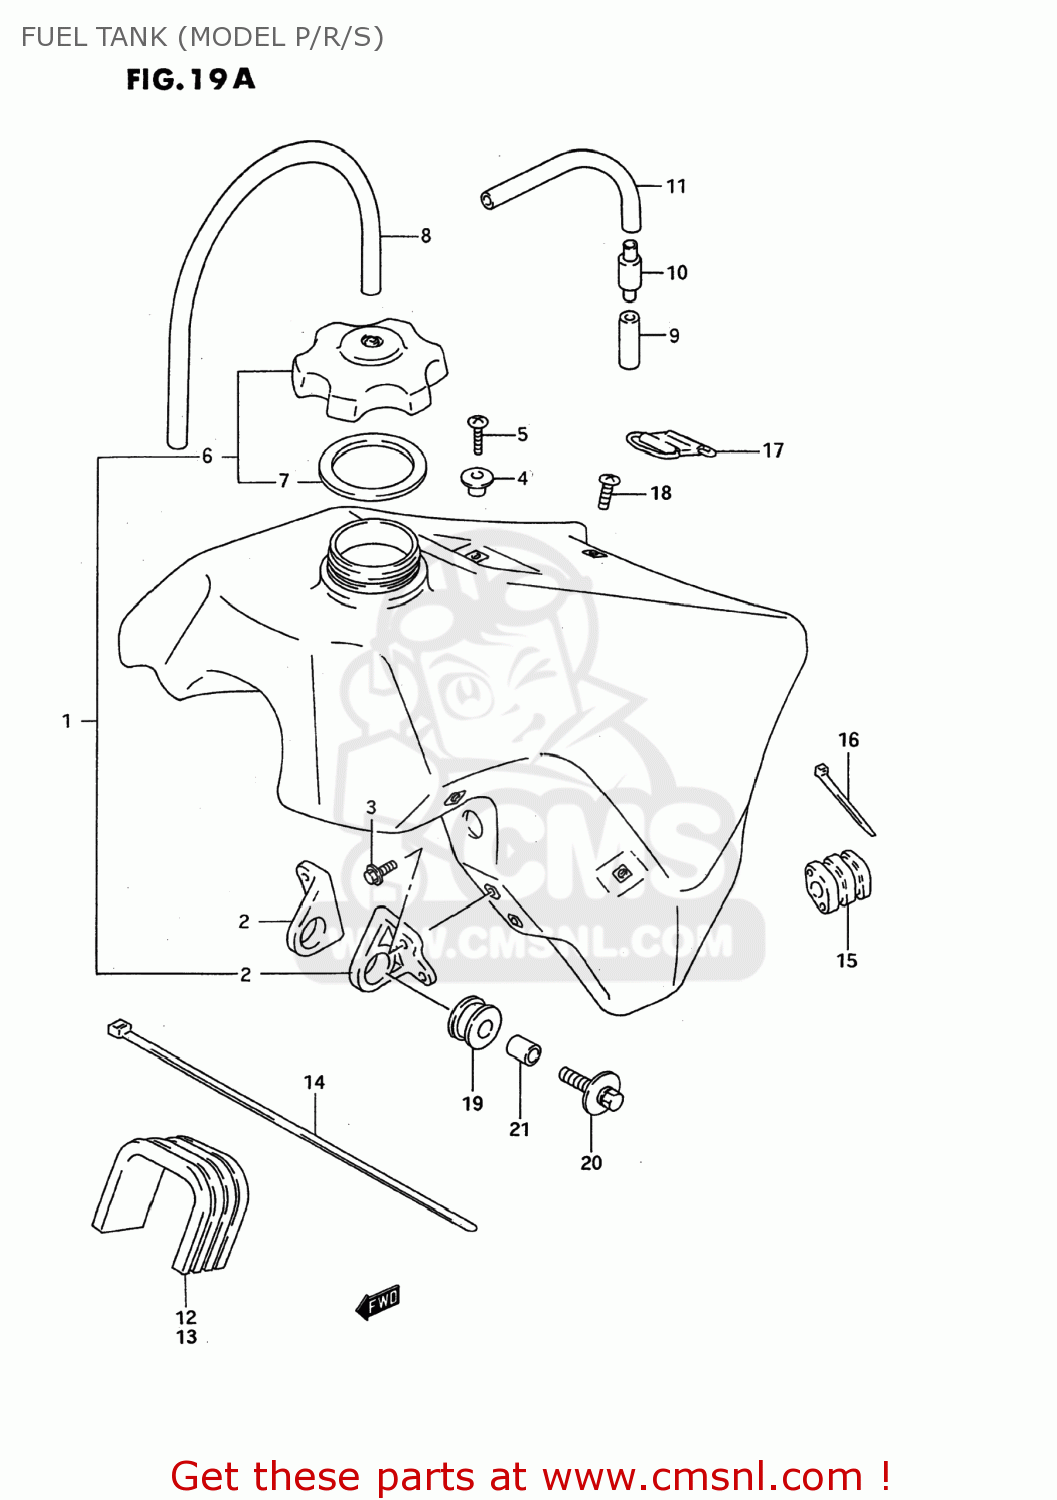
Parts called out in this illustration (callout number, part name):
1	TANK SET,FUEL
2	BRACKET,FUEL TANK FR
3	BOLT
4	HOOK,SEAT FR
5	SCREW
6	CAP SET,FUEL TANK
7	GASKET,CAP (NAS)
8	HOSE(5X8.2X600)
9	HOSE(5X8.2X600)
10	PLUG,FUEL TANK BREATHER
11	HOSE(5X8.2X600)
12	CUSHION,FUEL TANK NO.2
13	CUSHION,FUEL TANK
14	CLAMP(L:300)
15	CUSHION,FUEL TANK NO.2
16	CLAMP(L:145)
17	BAND,FUEL TANK RR
18	SCREW
19	CUSHION,MUFFLER
20	BOLT(6X30)
21	SPACER (6.4X9X13.5)
